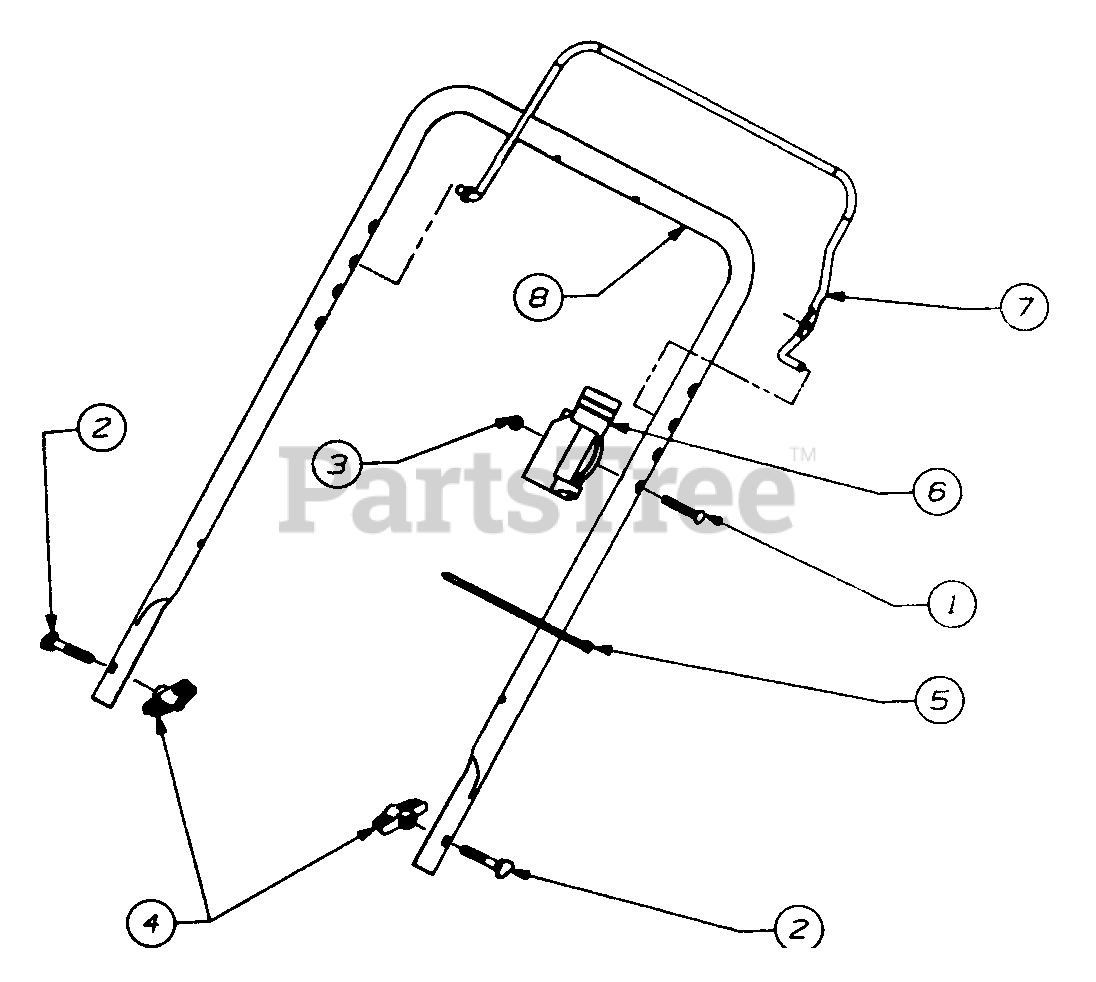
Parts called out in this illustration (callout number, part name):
1	Screw - Oval C-Sink L
2	Bolt Carriage
3	Nut Insl. Lock
4	Knob - Handle
5	Tie Cable
6	Body - Lever Control
